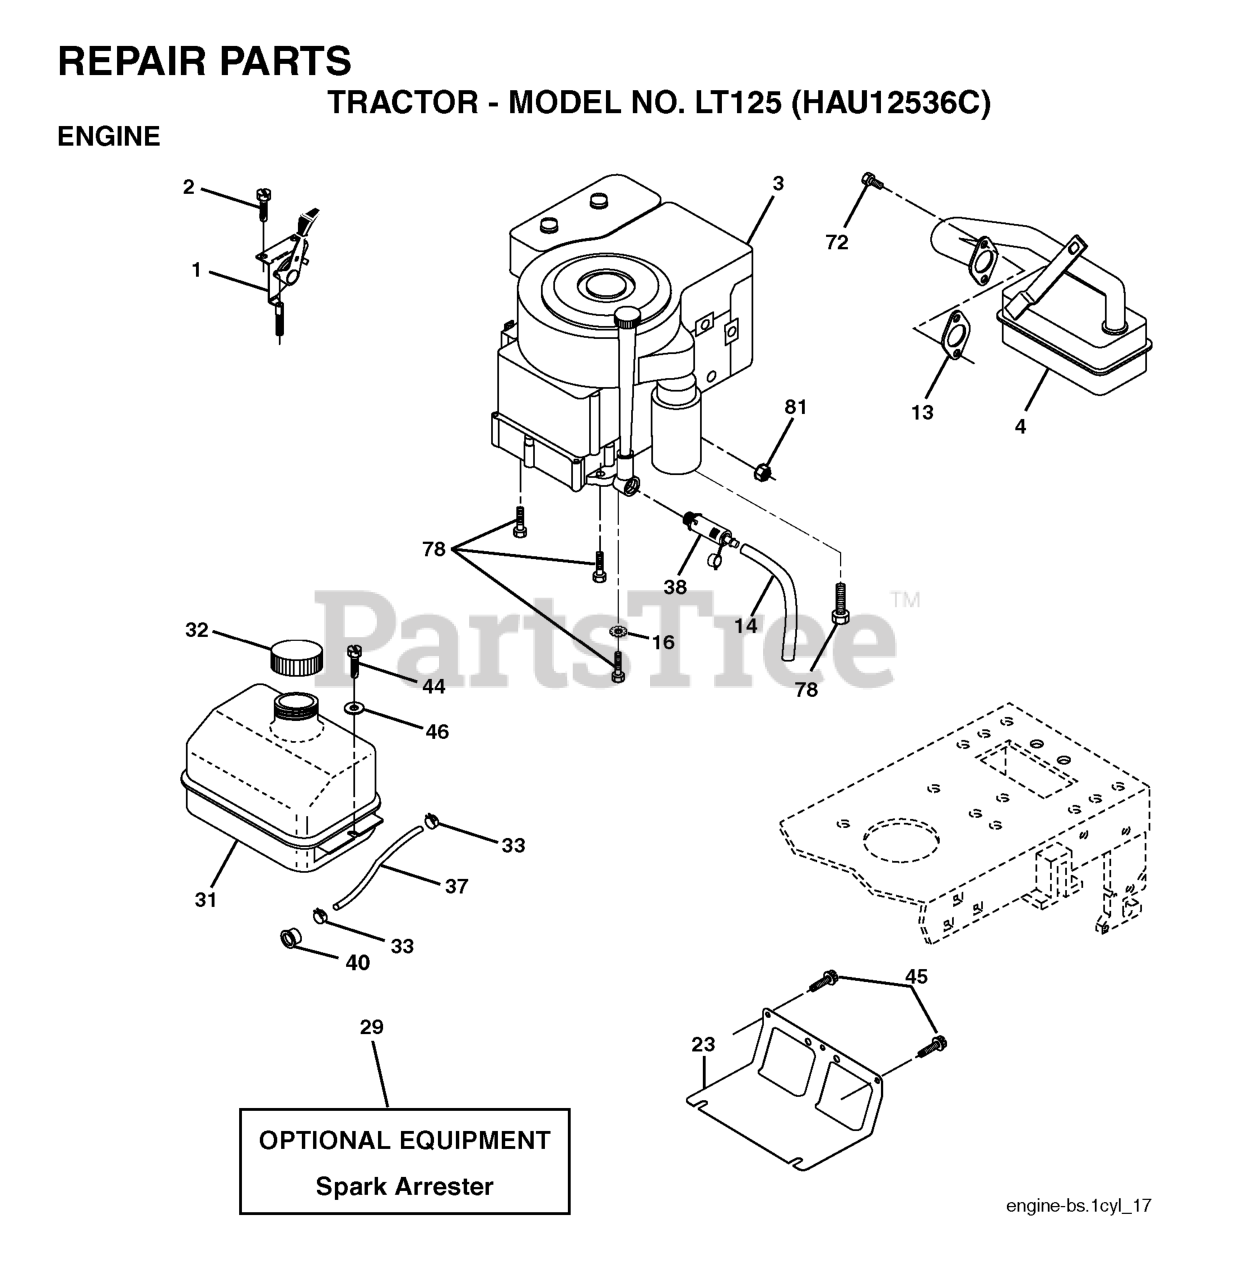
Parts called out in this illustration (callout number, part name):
1	CONTROL.THROTTLE/CHOKE.BLACK
2	SCREW
4	MUFFLER.B&S.MODEL.21.11HP.OHV
13	REPL BY 532 27 22-93
14	TUBE, DRAIN OIL ASM.
16	LOCKWASHER
23	SHIELD.BROWNING.DBR.GUARD
29	KIT.SPARK ARRESTOR 794945 B&S
31	TANK.ASM.FUEL.FRONT.W/CAP
32	FUEL CAP
33	HOSE CLAMP
37	LINE.FUEL.20
38	PLUG DRAIN OIL EASY
40	BUSHING.SNAP.NYL.BLK.
44	SCREW HEXWSHR 1/4-20X3/4
45	SCREW, 3/8-16X3/4
72	SCREW.SOCKET.HEAD.5/16-18
78	SCREW.3/8-16
81	NUT
